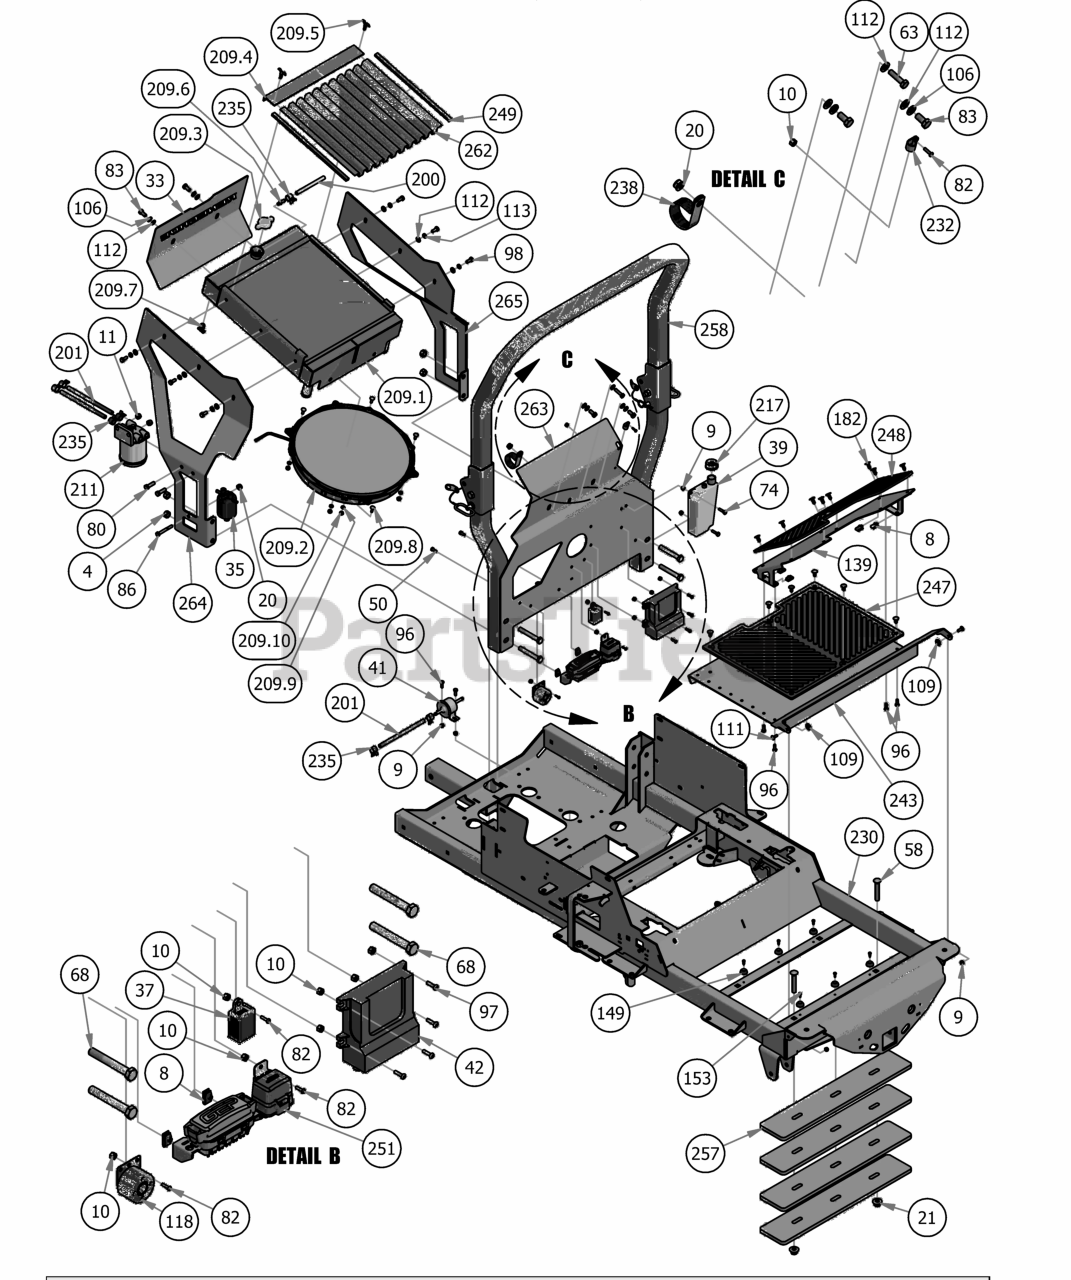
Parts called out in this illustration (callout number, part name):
4	1/2" Center Lock Nut
8	1/4-20 Cage Nut
9	1/4-20 Hex flang lock nut
10	10-24 Nylon Insert Locknut
11	3/8 Nylock Nut
20	5/16-18 Nylon Flange Nut
21	1/2-13 Nylon Flange Nut
33	2019 Diesel Upper Rear Cover
35	Caterpillar Fuel Bowl Kit
37	Auto Shut Down for Cat Diesels
39	overflow Reservoir- 27Kaw & 28/35Hp Diesel
41	Electric Fuel Pump
42	ECM for 1100cc Diesel
50	M6-1.0 X 16MM Hex Bolt
58	1/2-13 x 3 Carriage Bolt Grade 5
63	5/16 x 1 1/4 Hex Bolt
68	1/2 x 3 1/2 Flange Bolt Grade 8
74	1/4-20 x 1 GR 5 hex bolt zinc
80	3/8" x 1 1/4" Hex Bolt
82	10-24 X 5/8 BS Button Head Bolt
83	3/8" x 3/4" Hex Bolt
86	5/16" x 2 1/2" Bolt
96	1/4" x 3/4" Hex Bolt
97	10-24 x 1 BS C/S 18-8 SS
98	5/16" x 3/4" Hex Bolt
106	3/8" Lock Washer
109	.360 ID Plastic Washer
111	1/4" x 3/4" Carriage Bolt
112	5/16" Flat Washer
113	5/16" Lock Washer
118	Heat Warning Piezo Buzzer
139	2019 Outlaw Adjustable Foot Plate
149	Button Bumper
153	#10 x 1/2" Self Tapping Screw
182	Ratchet Fastener
200	5/16 Clear Hose x 42"
201	5/16 Fuel Line Hose - Priced Per Foot
209	2019 Diesel Radiator Kit
209.1	2019 Diesel Radiator
209.2	Electric Fan for 2019 Diesel Radiator
209.3	radiator cap
209.4	Screen Rentention Plate for 2019 Diesel Radiator
209.5	1/4-20 x 3/4 Thumb Screw
209.6	1/4 Barb to 3/16 NPT Overflow Fitting
209.7	1/4 NPT Drain Plug
209.8	1/4" x 3/4" Carriage Bolt
209.9	1/4" Lock Washer
209.10	1/4-20 Hex Nut
211	Fuel Filter
217	Reservoir Tank Cap-Overflow
230	2019 Horizontal Diesel Frame
232	3/8 Cable Clamp-Black Nylon
235	5/8 Hose Clamp
238	Diesel Clamp 1 3/4" Vinyl
243	2019 Outlaw Floorboard
247	OUTLAW2019_FLOORMAT
248	FLOORMAT_OUTLAW_2019
249	Rubber Trim
251	2019 24.7 Diesel Harness
257	2019 Outlaw Counter Weight
258	2019 2X2 Folding ROPS
262	Radiator Screen - Diesel
263	2019 Diesel Radiator Mount - Front
264	2019 Diesel Radiator Mount - Right
265	2019 Diesel Radiator Mount - Left
